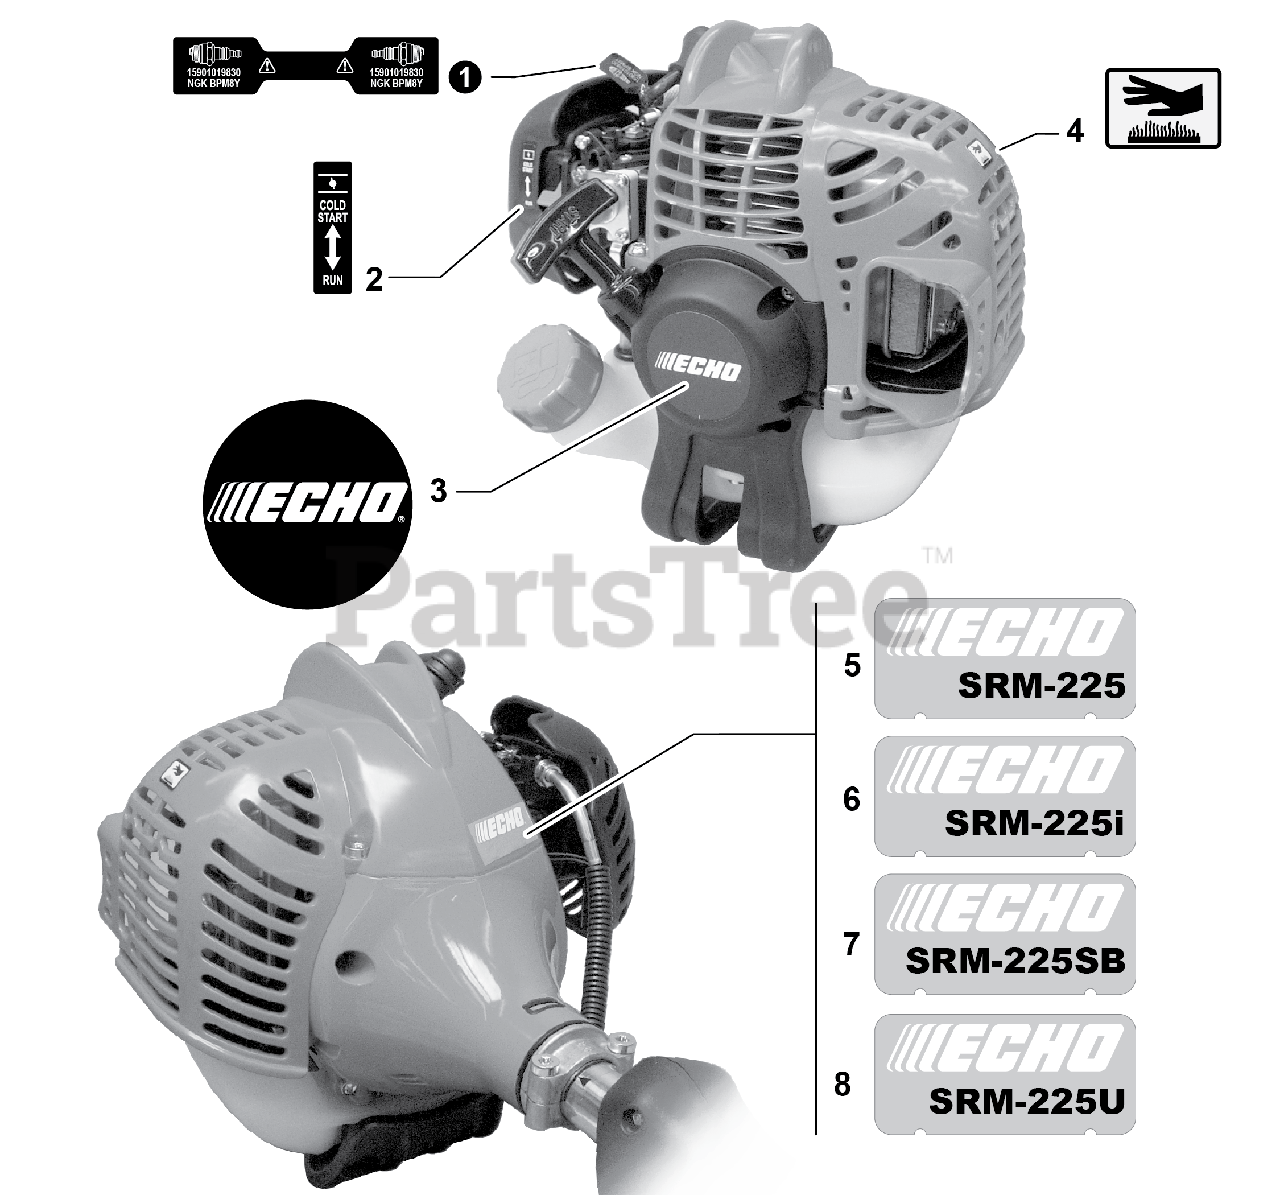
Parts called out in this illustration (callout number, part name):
1	LABEL, SPARK PLUG - BPM8Y
2	LABEL, CHOKE
3	LABEL, ECHO
4	LABEL, CAUTION - HOT
5	LABEL, MODEL SRM-225
6	LABEL, MODEL SRM-225i
7	LABEL, MODEL SRM-225SB
8	LABEL, MODEL SRM-225U
